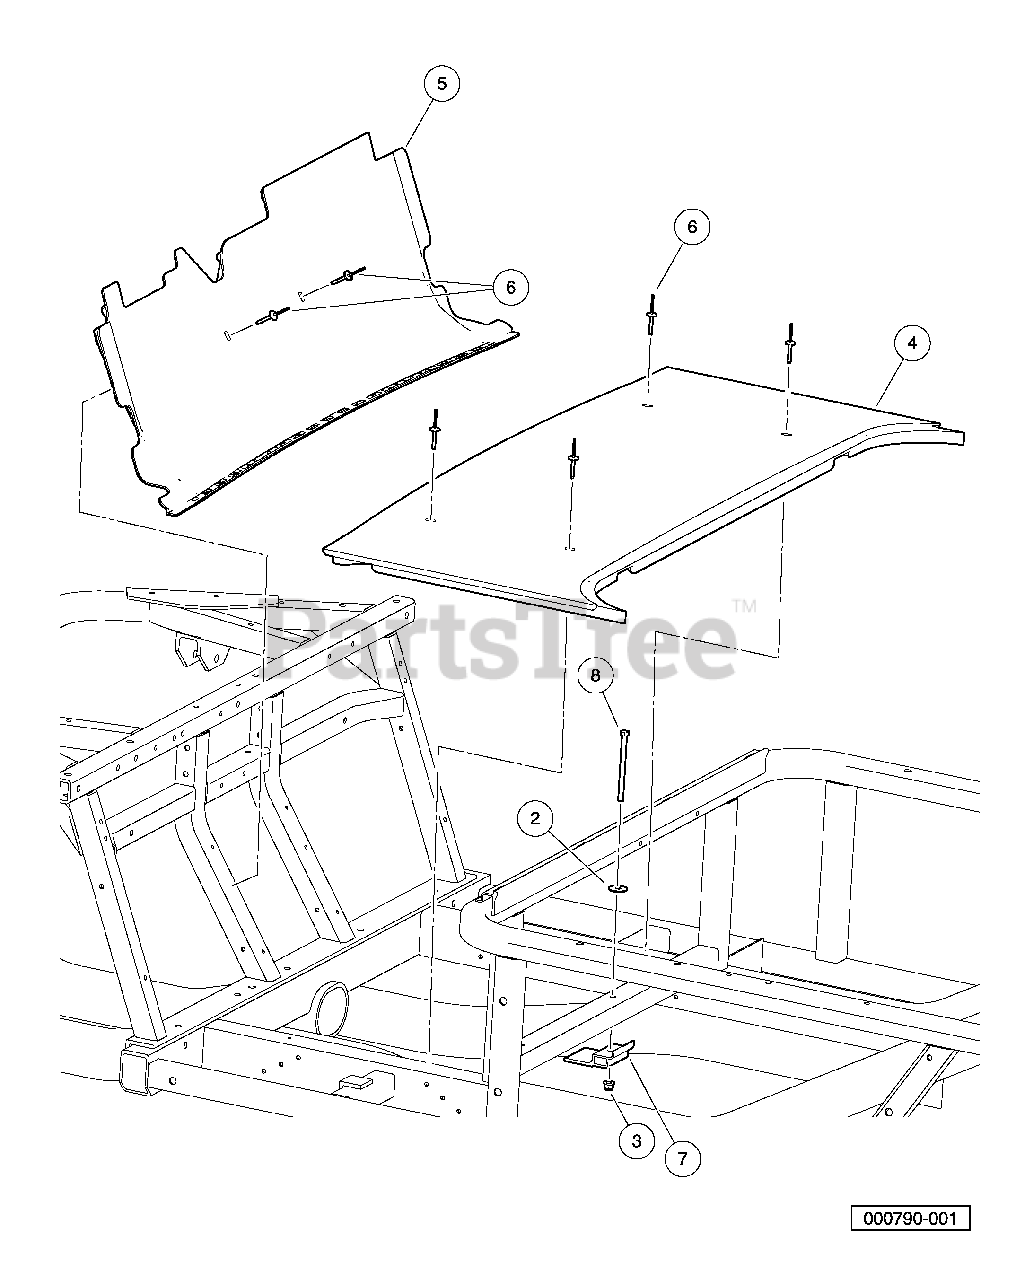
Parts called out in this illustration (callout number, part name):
1	Instl, Floorboard
2	Washer, 5/16 Type B Flat
3	Lock Nut, Flg M8 X 1.25 Nylon
4	Floorboard, Lower
5	Floorboard, Upper
6	3/16 X 1.19 Alum Rivet, Blk
7	Bracket, Support, Floorboard
8	Bolt, M8 X 1.25 X 110
